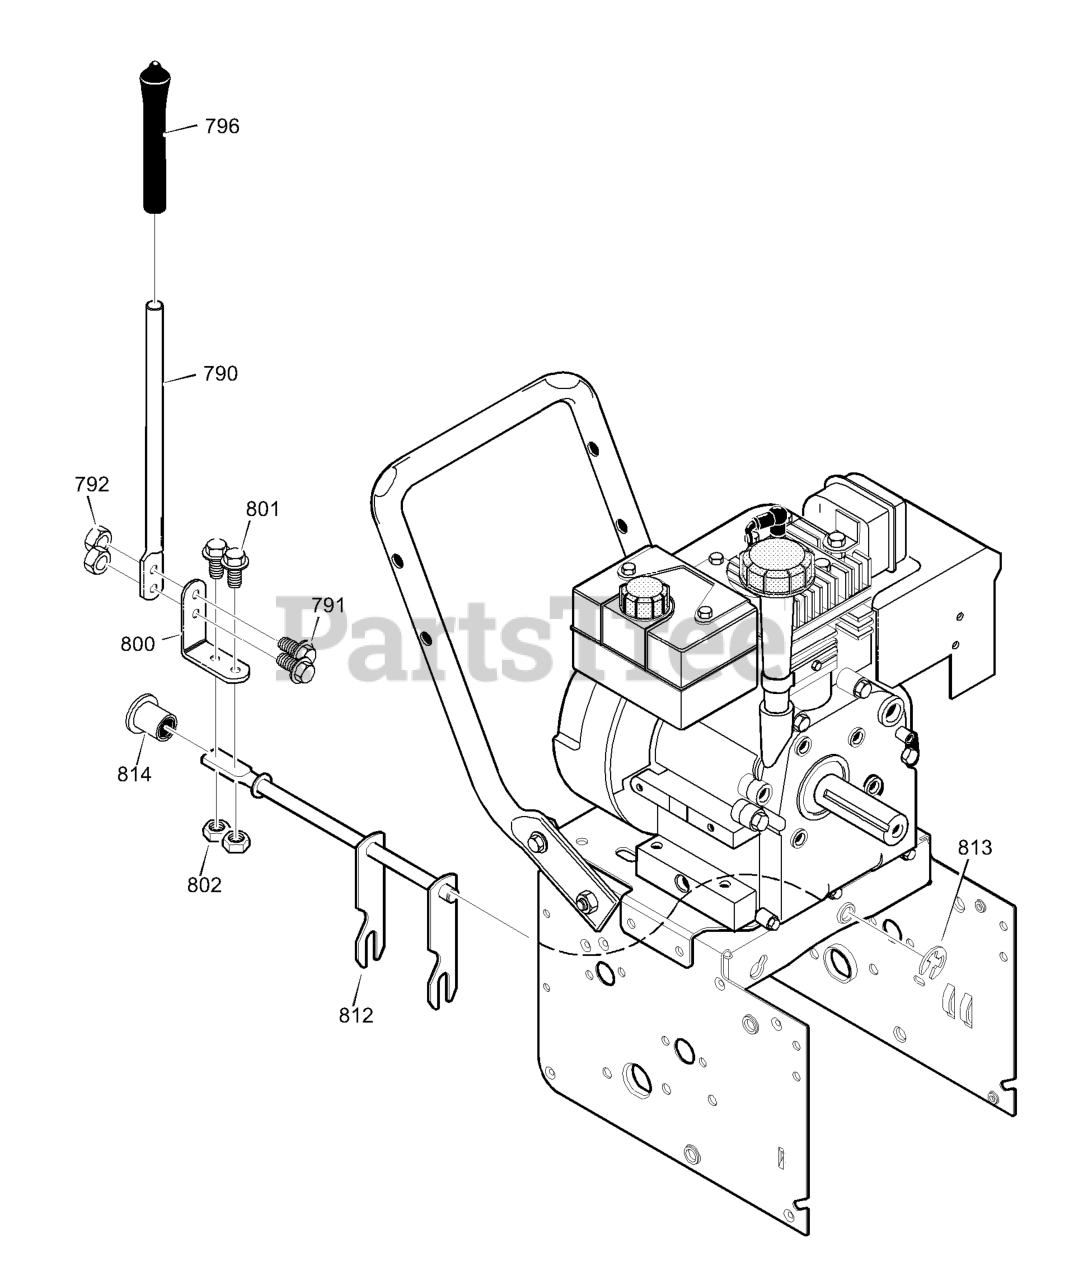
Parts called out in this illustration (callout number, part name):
790	ROD, SHIFT
791	SCREW, 1/4-20X.75
792	NUT, 1/4-20
796	KNOB, SLIP
800	LEVER, SPRING
801	SCREW, 1/4-20X.75
802	NUT, 1/4-20
812	ROD ASSY., SPEED SELECT
813	RETAINER, RING
814	BEARING, FLANGED
